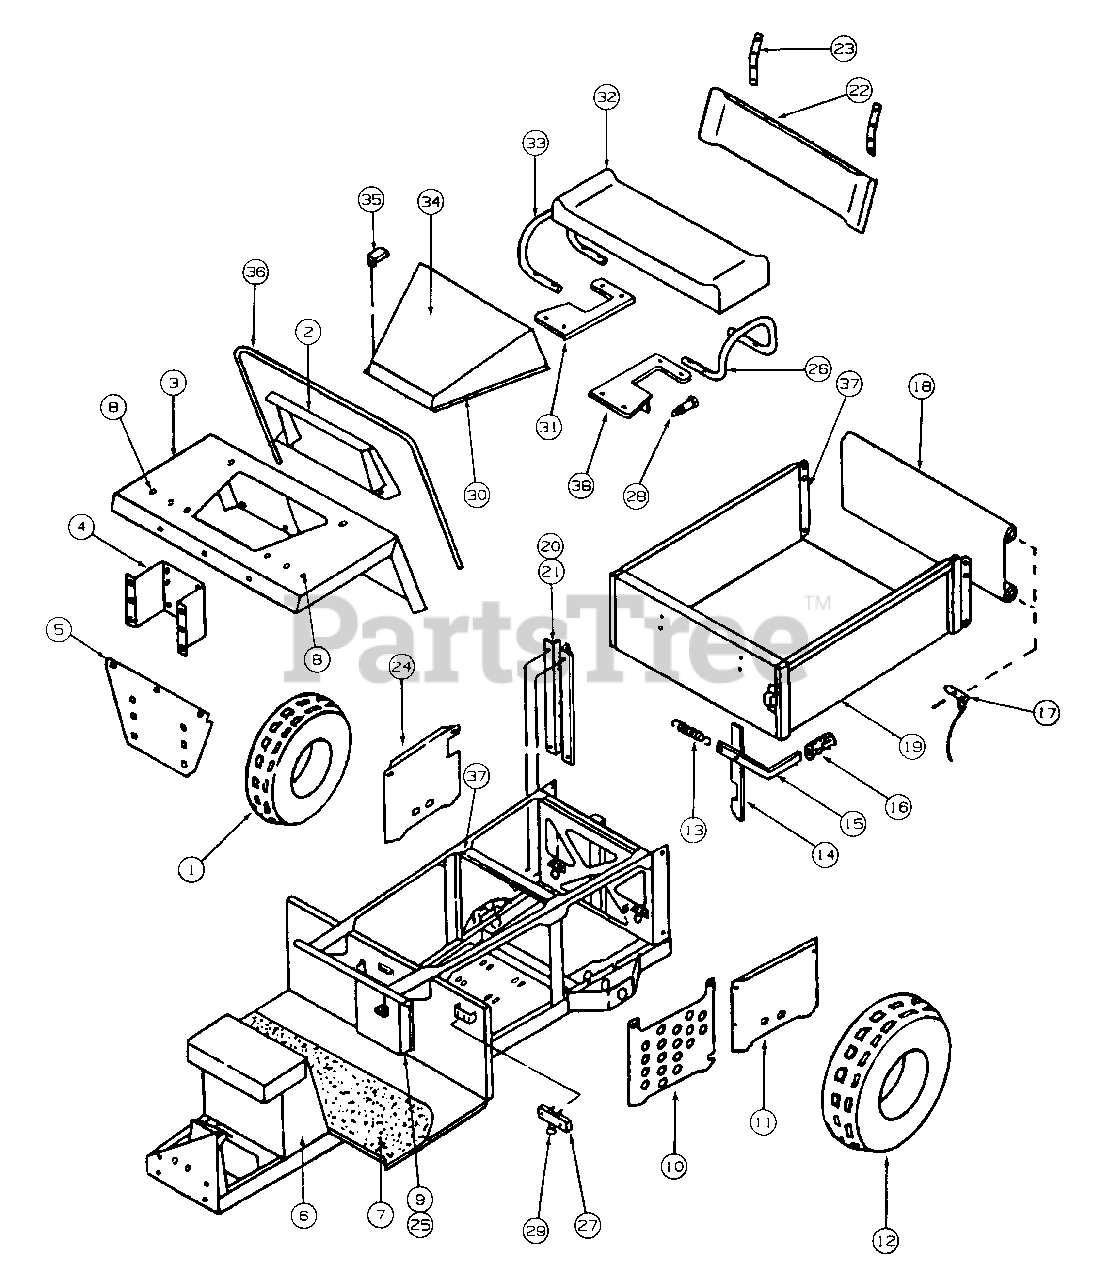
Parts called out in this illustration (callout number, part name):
1	Tire/Rim, Front Knob
2	Panel, Dash
5	Grill, Front
6	Frame Assy
7	Mat, Floor
8	Plug, Hole
9	Glove Box, Vertical
10	Panel, Center Access
11	Panel, Left Rear Access
12	Tire/Rim, Rear Big Knob
13	Spring, Latch
14	Catch, Lift Latch
15	Arm, Dump Box Latch
16	Grip, Flat
17	Pin/Cable Assy, Tailgate
20	Transaxle Mount, LH Frt
21	Transaxle Mount, RH Frt
22	Seat, Bench Back
23	Bracket, Seat Back Mtg
24	Panel, Right Rear Access
26	Hand Rail, LH Seat
27	Latch, Seat
28	Bolt, Strike
30	Foam Strip
31	Plate, RH Seat Spacer
32	Bottom, Seat
33	Hand Rail, RH Seat
37	Tape, Foam
38	Plate, Lh Seat Spacer
